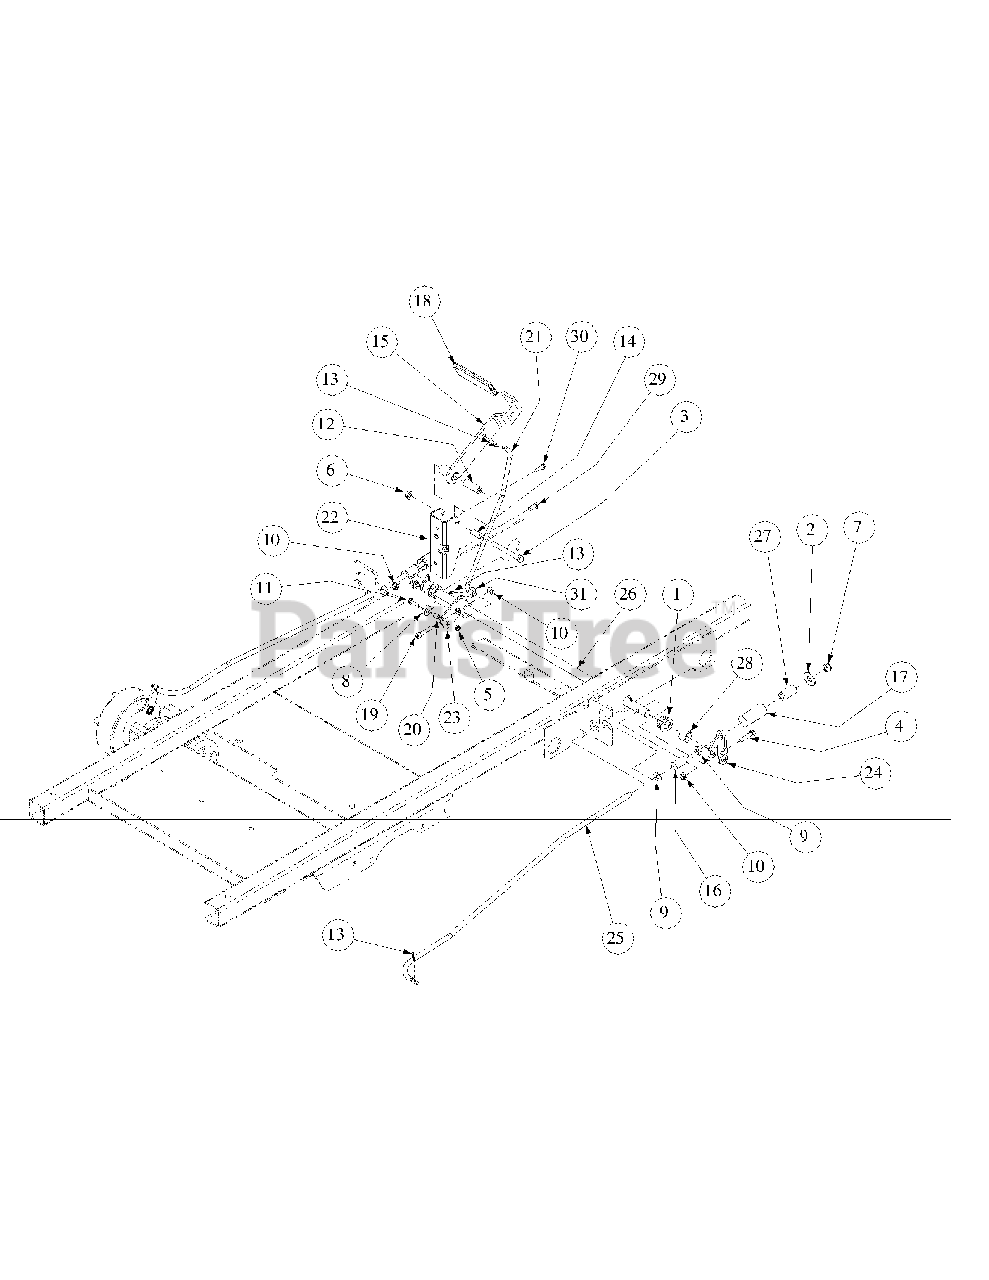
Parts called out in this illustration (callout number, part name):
1	Hex Flange Bearing, .752 ID
2	Flat Washer, 1/2
3	Hex Cap Screw, 3/8-16 x 3-1/4
4	Hex Cap Screw, 5/16-18 x 1-1/2
5	Lock Nut, 1/4-20, Nylon Insert
6	Flange Lock Hex Nut, 3/8-16
7	Nylock Nut, 7/16-14
8	Spacer, Control Rod
9	Washer, .469 ID x .875 OD x .105
10	Hex Flange Lock Nut, 5/16-18
11	Self Tapping Screw, 1/4-20 x 1.00
12	Spacer, .39 x .63 x 1.75
13	Cotter Pin, .072 x 1.12 Lg
14	Spacer, .375 x .50 x .75 Lg
15	Brake Handle
16	Neutral Brake Spring
17	Force Brake Spring
18	Parking Brake Grip
19	Socket Head Cap Screw, 5/16-18 x 1.50
20	Spacer, .375 OD x .257 ID x .438
21	Brake Rod
22	Parking Brake Mounting Bracket
23	Brake Arm Assembly
24	Brake Bracket
25	Linkage Brake Rod
26	Pivot Brake Shaft
27	Low Pressure Hose
28	Spacer, .76 ID x 1.0 OD x .75
29	HHCS, 5/16-18 x 1.0
30	Screw, TT, 1/4-20, 0.75, Hex Index Washer
31	Flat Washer, .406 ID, 1.0 OD, .105
